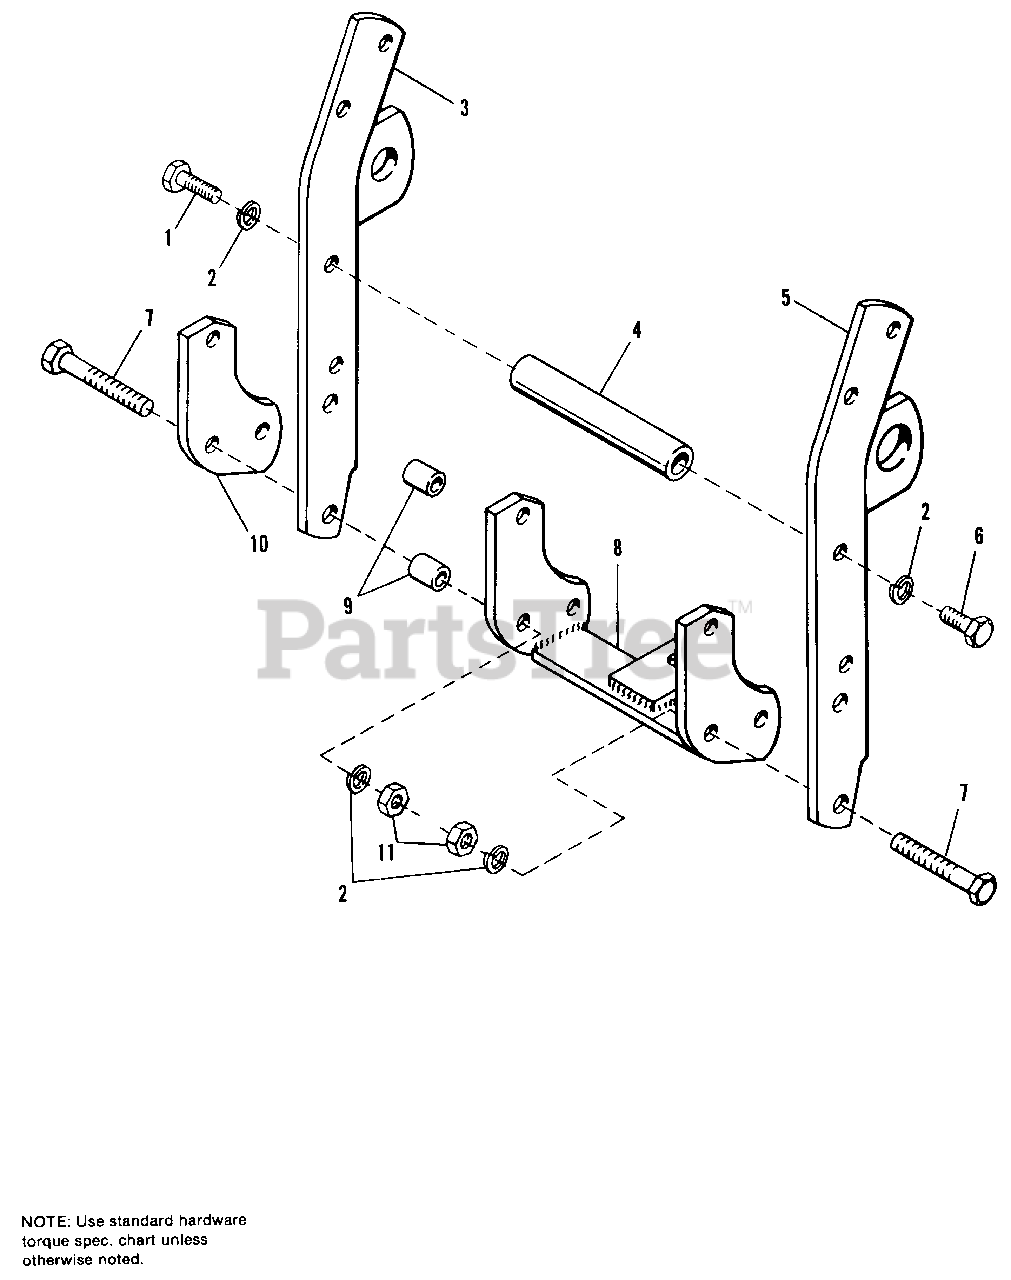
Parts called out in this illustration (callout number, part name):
1	CAPSCREW, Hex Hd., 7/16-14 x 1-3/4
2	LOCKWASHER, 7/16
3	BAR ASSY., Upright
5	BAR ASSY., Upright
6	CAPSCREW, Hex Hd., 7/16-14 x 1-1/4
7	CAPSCREW, Hex Hd., 7/16-14 x 2-3/4
8	BAR ASSY., Draw
11	NUT, Hex, Full, 7/16-14
